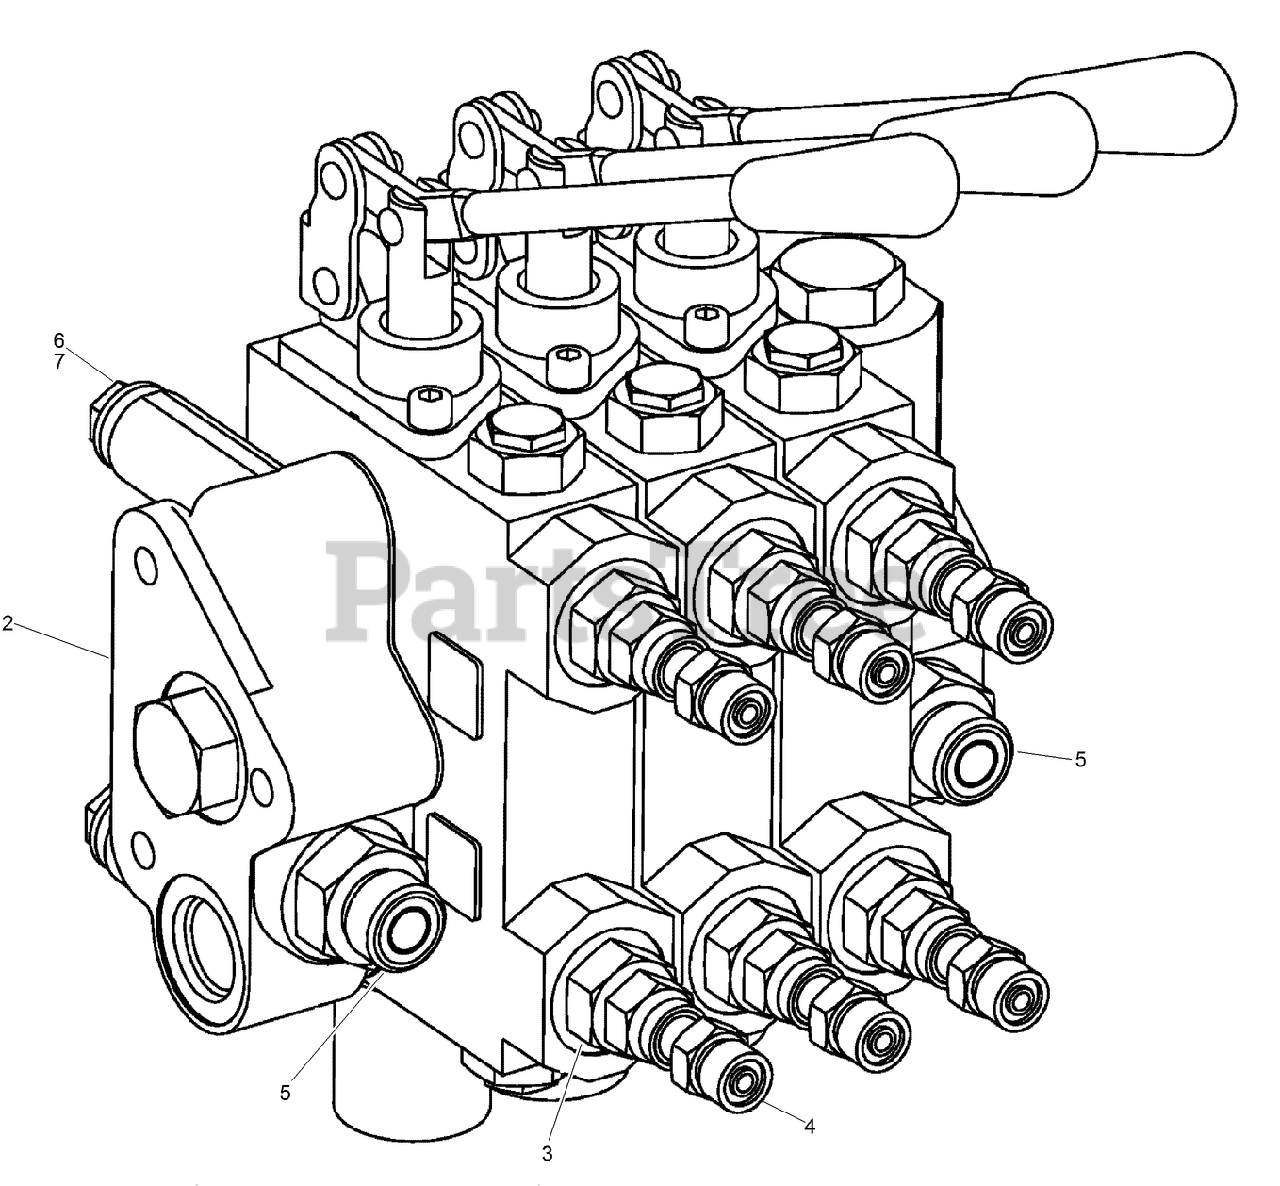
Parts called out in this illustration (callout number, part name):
2	3 SPOOL HYD VALVE ASM
3	CONNECTION - Straight, -4 ORFS / -8 ORB
4	FITTING-STRAIGHT
5	CONNECTION - Straight, -8 ORFS / -10 ORB
6	WASHER-FLAT
7	BOLT
